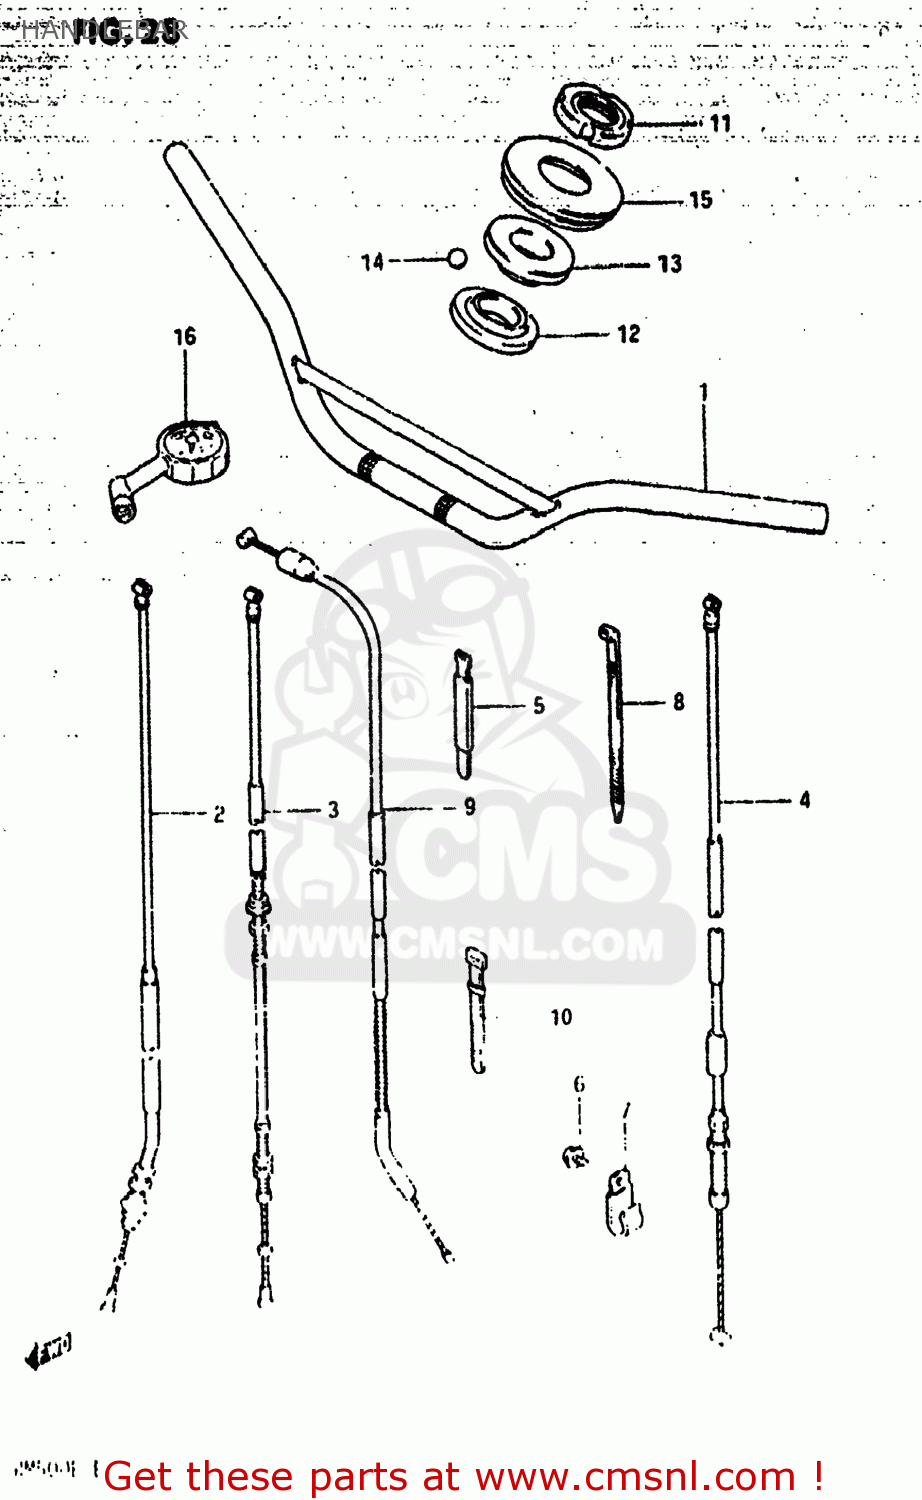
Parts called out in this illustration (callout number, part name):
1	HANDLEBAR
2	CABLE ASSY,FR BRAKE
3	CABLE,FR BRAKE
4	CABLE ASSY,CLUTCH
5	CLAMP
6	SCREW
7	CLAMP
8	CLAMP
9	CABLE ASSEMBLY,THROTTLE
10	CLAMP(L:187)
11	NUT,STEERING STEM
12	RACE,STEERING,INNER,UPPER
13	RACE,STEERING,OUTER,UPPER
14	BALL
15	SEAL,STEERING UPR DUST
16	GAUGE ASSY,AIR PRESSURE
